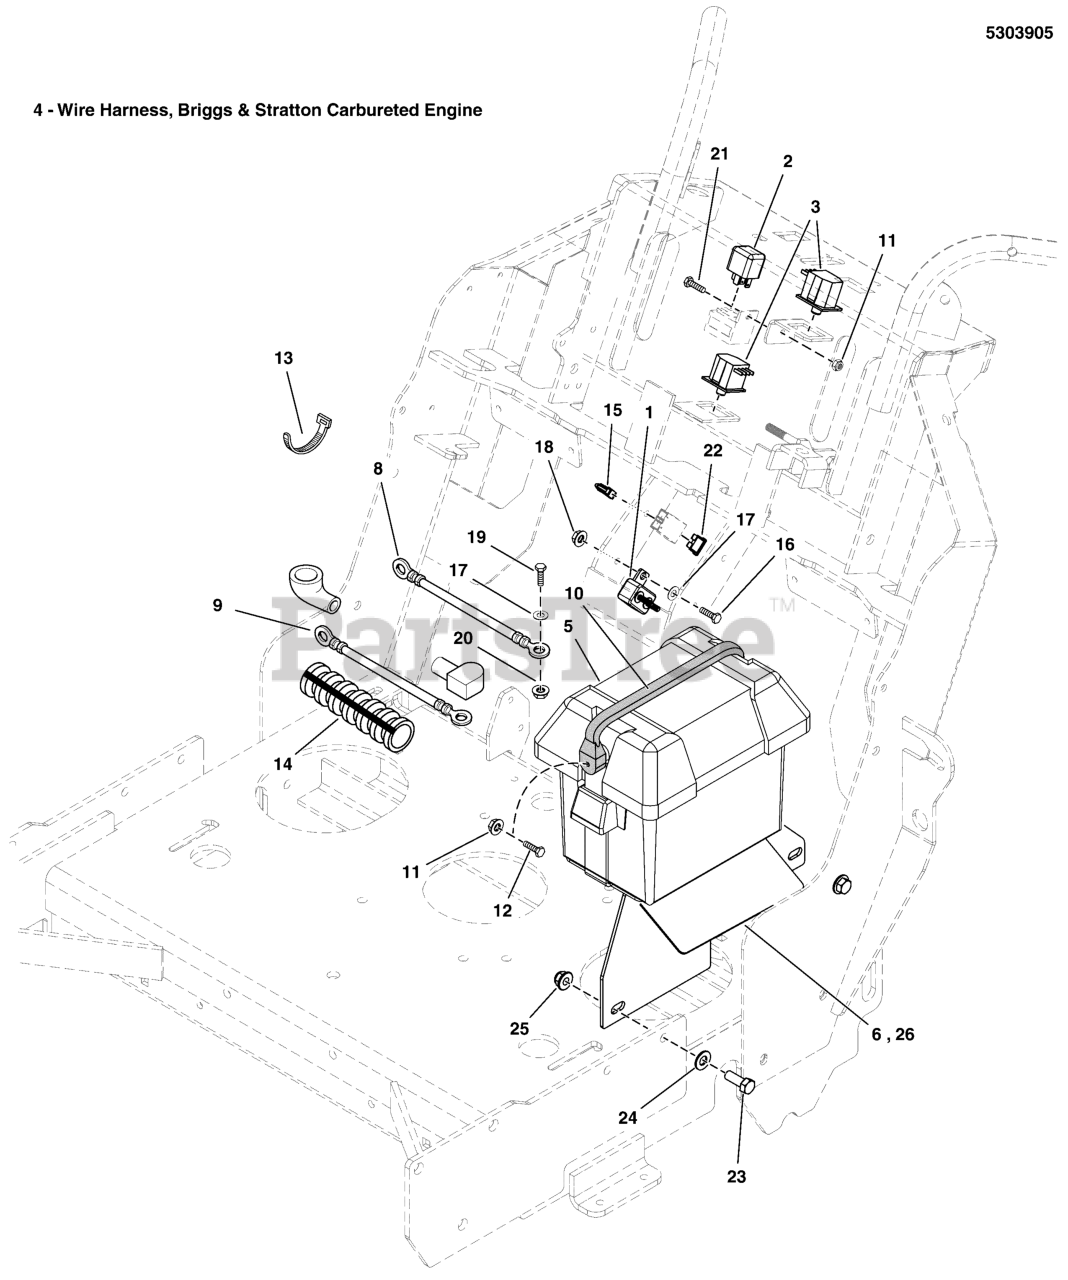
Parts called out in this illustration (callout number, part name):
1	BREAKER-CIRCUIT 12VOLT 20AMPS W/TAB
2	RELAY, 12 VOLT, 40 AMP
3	SWITCH, PLUNGER, NO/NC SNAP-IN, LOW PROFILE
4	WIRE HARNESS, SW35, BV, NO BRAKE
4	HARNESS, WALK BEHIND, WIRING
5	BATTERY BOX, W/ DRAIN HOLE
6	WELD, BATTERY MOUNT, SW35 - BLK
7	BATTERY, WET ( BCIU1, 350 CCA)
8	CABLE, BATTERY, NEG, 30, 1/4-5/16
9	BATTERY CABLE, POS, 35, 1/4-5/16
10	STRAP, RUBBER
11	NUT, Hex, Nylon Lock, #10-24
12	SCREW, #10-24 X 1 RS, CZ
13	TIE, SELF-LOCKING, 12"
14	WIRE LOOM, 3/8 ID X 27" LONG
15	FIR TREE MOUNT, PACKARD
16	BOLT, 1/4"-20 X 3/4" GD5 YZ
17	WASHER, 1/4 SAE
18	NUT, 1/4-20 Hex Nylock Flange
19	HHCS, 1/4-20 X 0.625, GR5, ZINC/CLEAR
20	NUT, 1/4-20 HEX SERR. FLANGE
21	SCREW, #10-24 X 1/2" ROUND PHILLIPS
22	FUSE, ATO-15 (15 AMP)(SV)
23	BOLT, 3/8-16 X 1" GD5 CZ
24	WASHER, 3/8 SAE
25	NUT, 3/8 - 16 HEX NYLOCK FLANGE
26	WELD, BATTERY MOUNT, W35 - BLK
